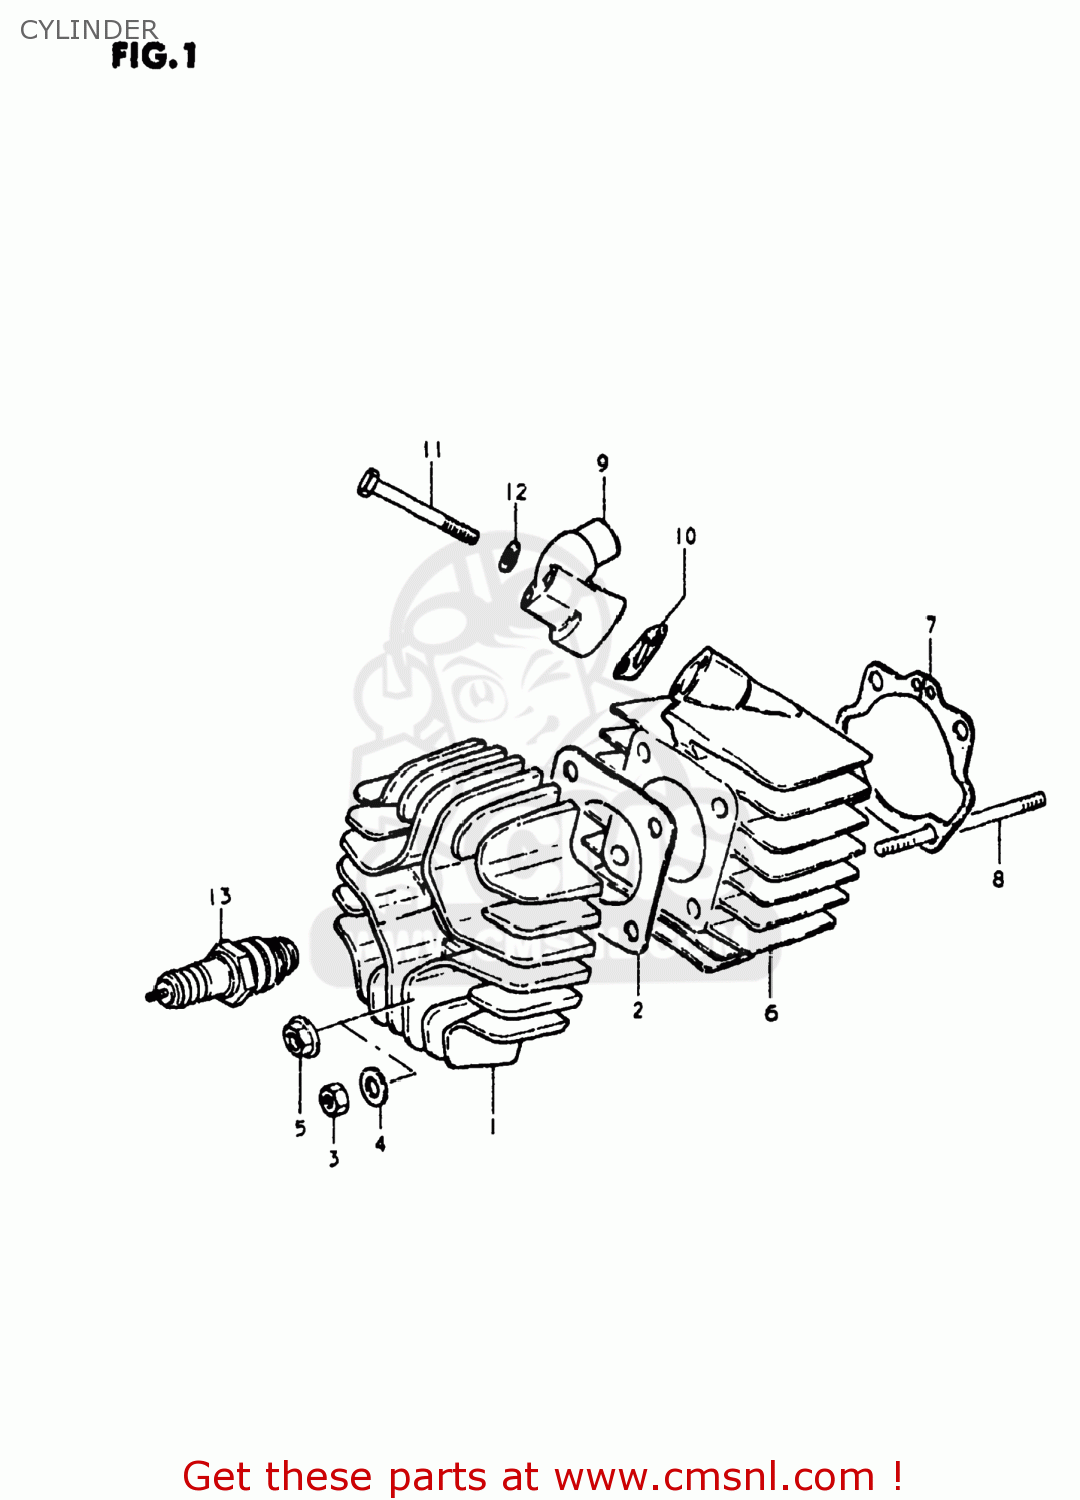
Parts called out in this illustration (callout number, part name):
1	HEAD,CYLINDER
2	GASKET,CYLINDER HEAD (NAS)
3	NUT
4	WASHER
5	NUT
6	CYLINDER
7	GASKET,CYLINDER (MCA)
8	STUD BOLT
9	PIPE,INTAKE
10	GASKET (NAS)
11	BOLT
12	LOCK WASHER
13	SPARK PLUG
